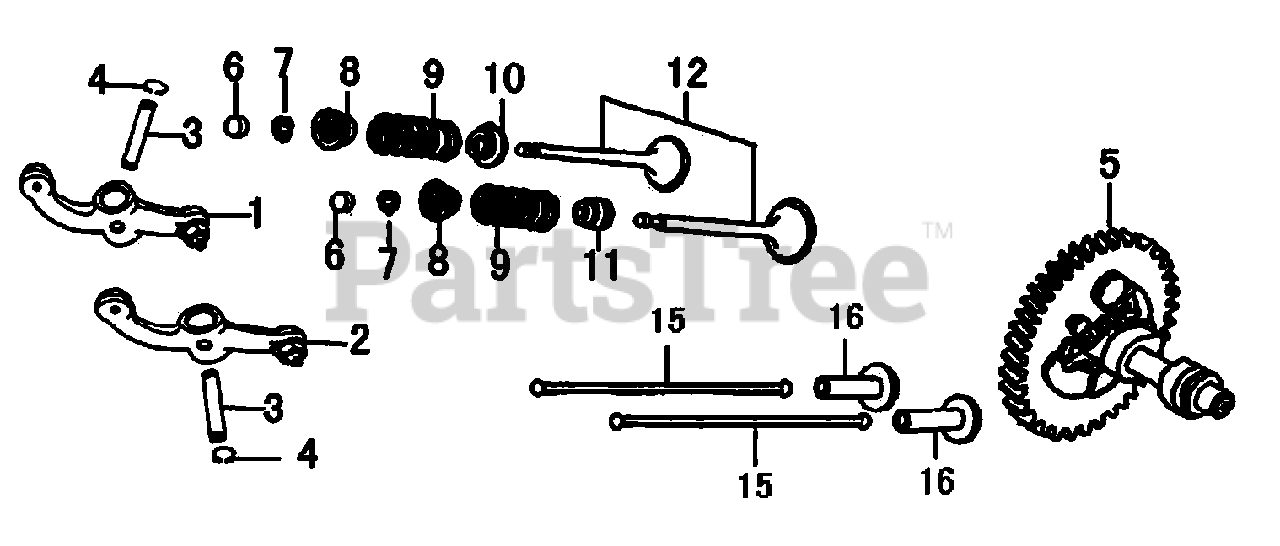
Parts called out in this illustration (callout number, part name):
1	ROCKER ARM (EXHAUST)
2	ROCKER ARM (INTAKE)
3	ROCKER SHAFT
4	ROCKER LOCKER
5	CAMSHAFT ASSY
6	ROTATOR, VALVE
7	VALVE LOCKER
8	RETAINER, VALVE SPRING
9	SPRING, VALVE
10	SEAT, VALVE SPRING
11	SEAL, VALVE STEM INTAKE VALVE
12	VALVES, INTAKE&EXHAUST SET OF 2
16	LIFTER, VALVE
